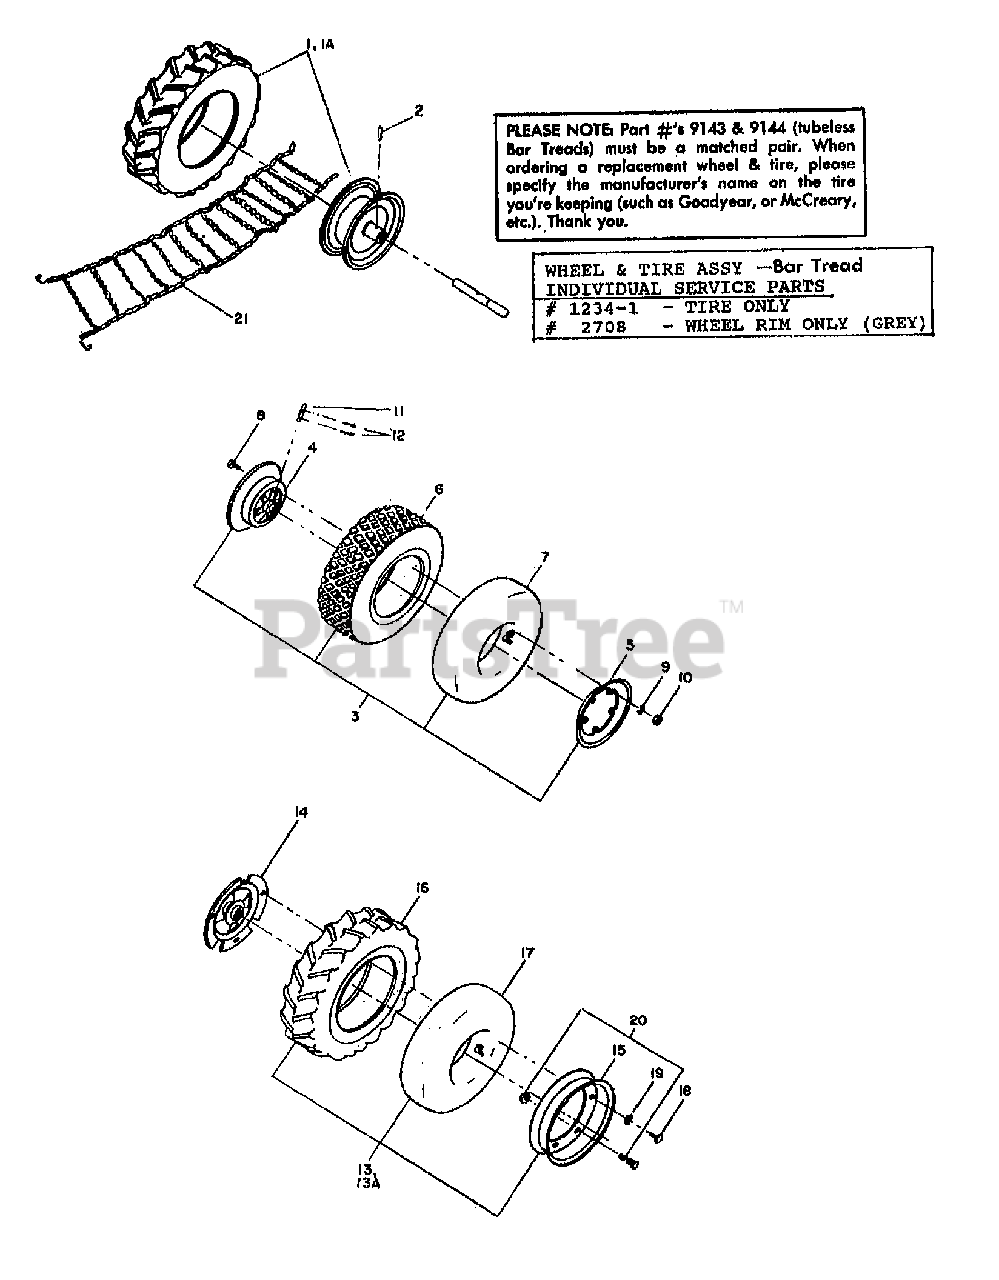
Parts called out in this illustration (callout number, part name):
1	TIRE-RT BT GARDEN TRAC
1A	TIRE-LT BT GARDEN TRAC
2	PIN-SPIROL .313 X 1.5
3	4X7TIRE/TUBE
4	HUB-4X7
5	WHEEL RIM
6	TIRE 4X7
7	TUBE-4X7
8	SCR-HH 3/8-16X1.25
9	WASHER-LK .375 @ DEPL
10	NUT-HEX 3/8-16 ZP
11	KIT-NUT/BOLT PIN WHL/SHAFT
12	PIN-COTTER .094X1.0
13	ASSM-WHEEL 4X8 BTT
13A	ASSM-RT WHL BTT
14	HUB-WHEEL MACH
15	RIMS W/HDW (1648)
16	TIRE-BTT 4.80/4.00X8.00
17	TUBE-INNER BT (4 X 8)
18	SCR-HH 3/8-16X.75 G5 ZP
19	WASHER-LK .375 @ DEPL
20	STUD & NUT
21	CHAINS-HORSE TILLER
